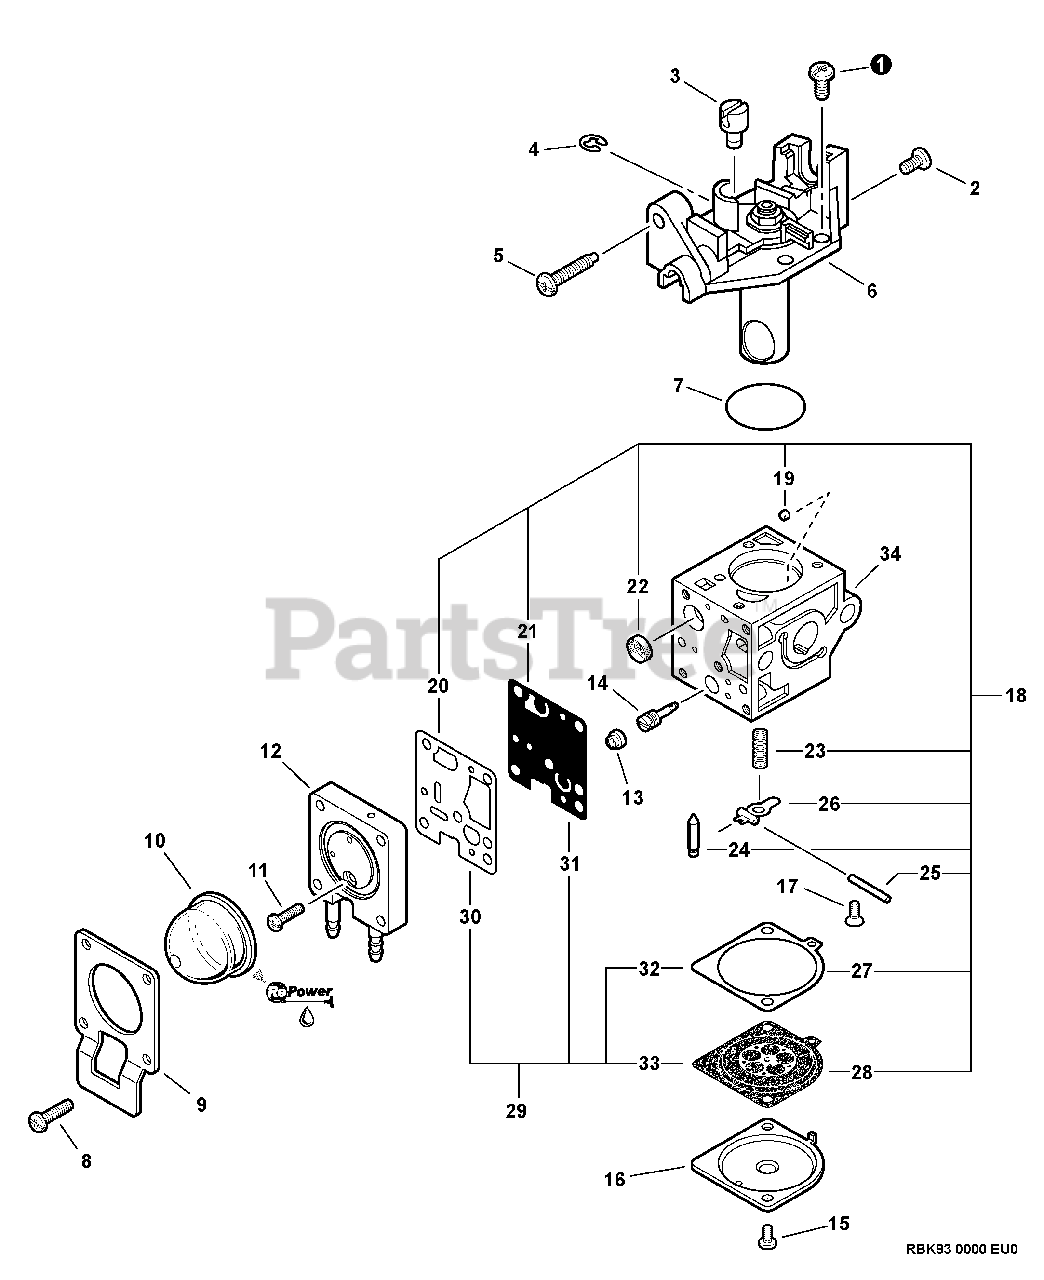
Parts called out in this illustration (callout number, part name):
5	SCREW, IDLE ADJUST
6	COVER ASSY, ROTOR
9	RETAINER, PURGE BULB
10	BULB, PURGE
12	BODY ASSY, PURGE
14	NEEDLE, HIGH SPEED
16	COVER, METERING DIAPHRAGM
18	REPAIR KIT
19	GUIDE, ROLLER
20	GASKET, PUMP
21	DIAPHRAGM, PUMP
22	STRAINER
23	SPRING, METERING LEVER
24	VALVE, INLET NEEDLE
25	PIN, METERING LEVER
26	LEVER, METERING
27	DIAPHRAGM, METERING
28	GASKET, DIAPHRAGM
29	GASKET / DIAPHRAGM KIT
30	GASKET, PUMP
31	DIAPHRAGM, PUMP
32	DIAPHRAGM, METERING
33	GASKET, DIAPHRAGM
34	BODY, CARBURETOR
